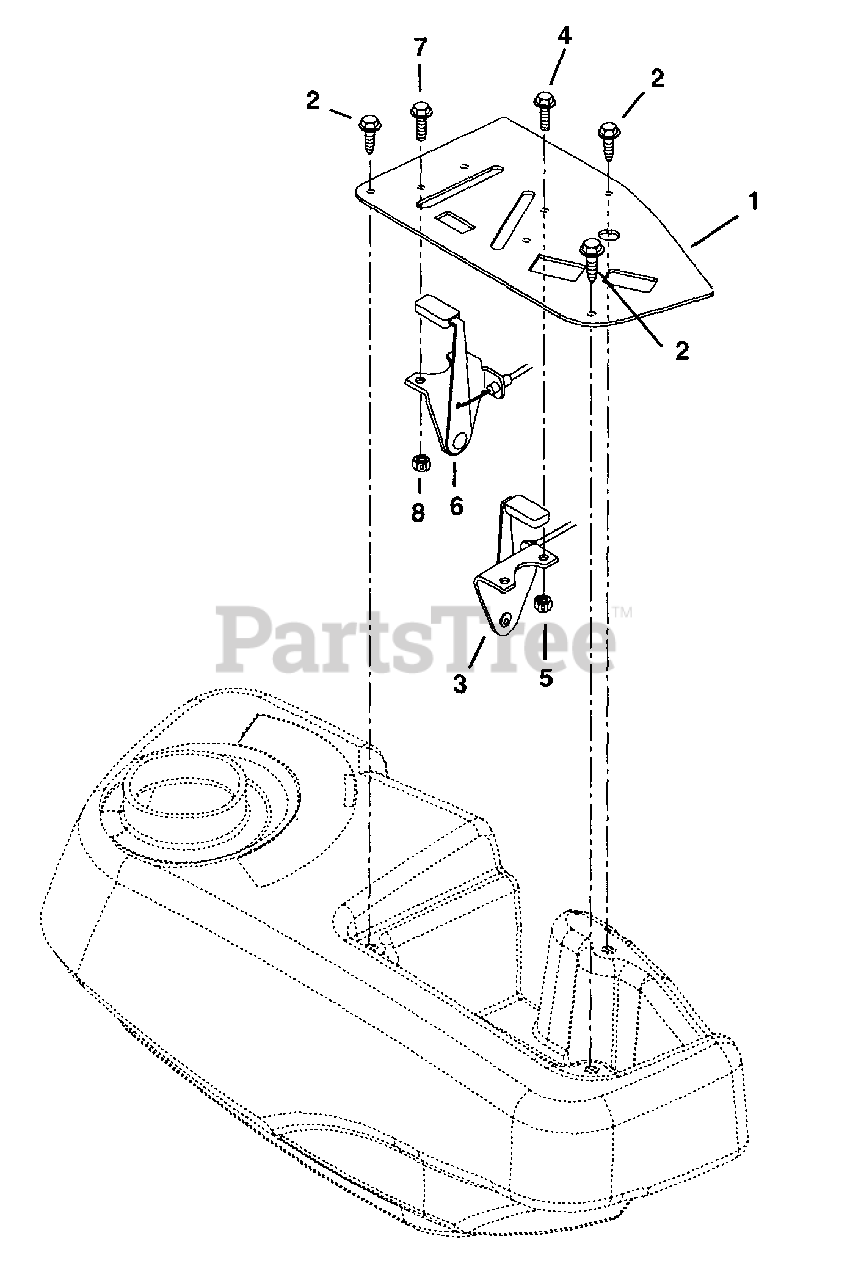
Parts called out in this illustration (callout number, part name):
1	Panel-Control
2	Screw-Machine 10-24 x .50 Hex Washer Head
3	Throttle Control
4	Screw-Machine 10-24 x .50 Hex Washer Head
5	Nut-Locking-Nylon 10-24 With Insert
6	Choke Control
6	Choke-Control
7	Screw-Machine 10-24 x .50 Hex Washer Head
8	Nut-Locking-Nylon 10-24 With Insert
